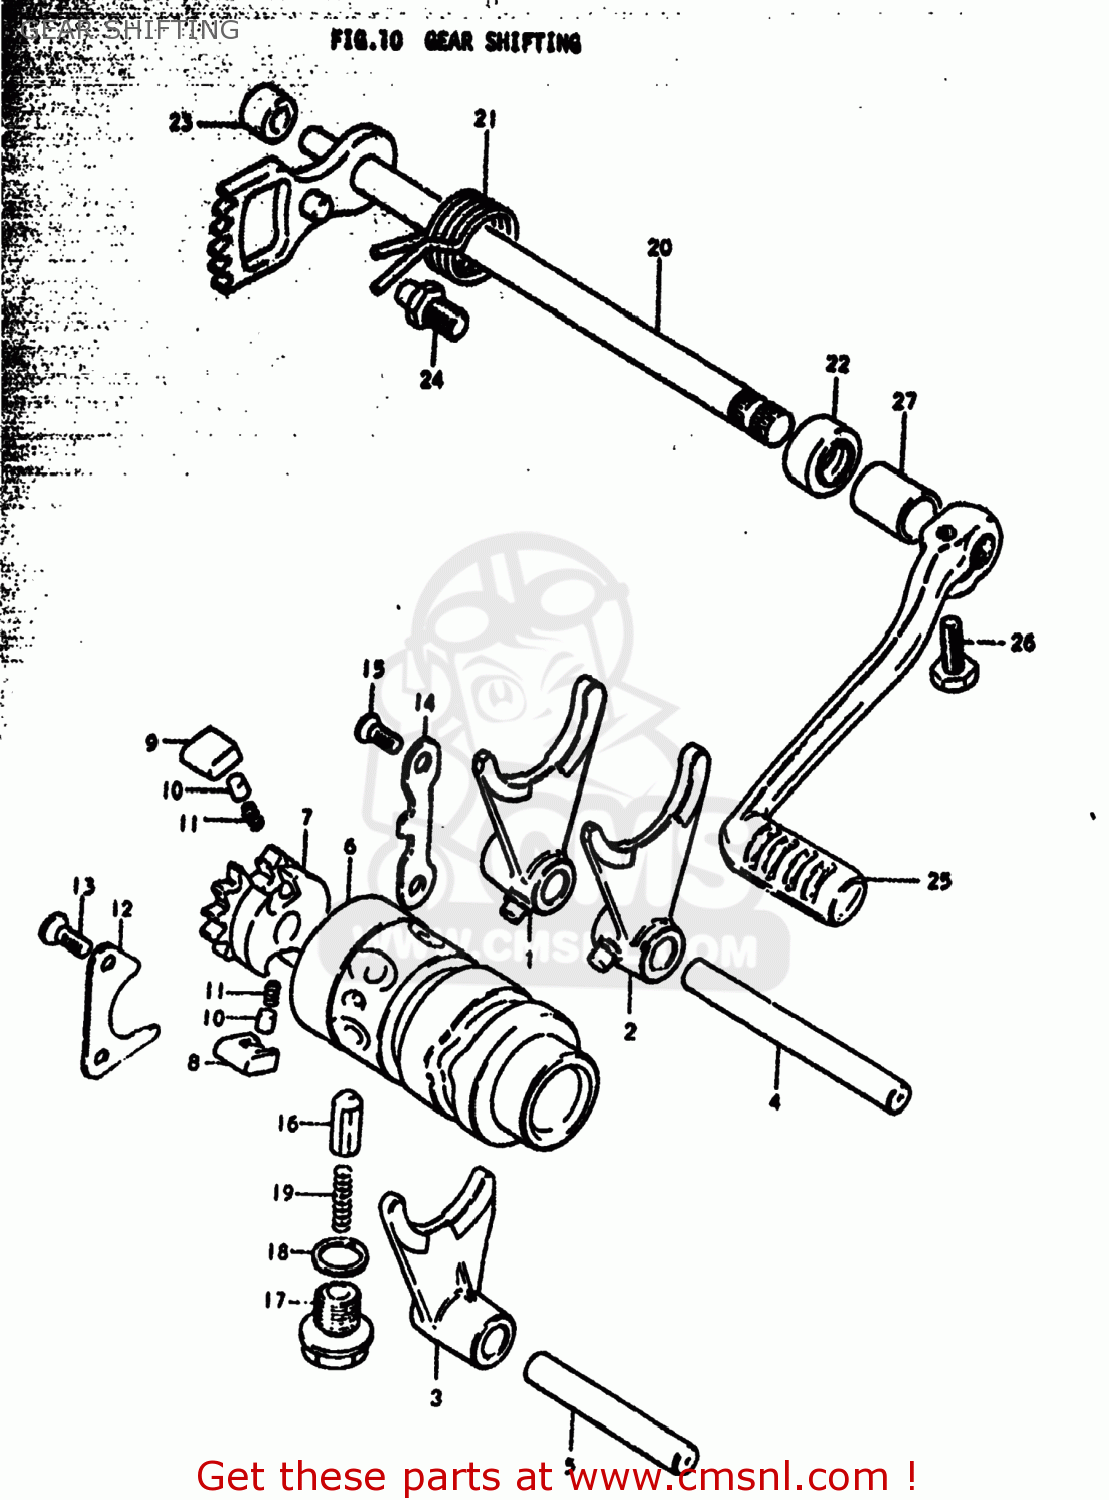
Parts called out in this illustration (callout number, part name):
1	FORK,GEAR SHIFT NO.1
2	FORK,GEAR SHIFT NO.2
3	FORK,GEAR SHIFT NO.3
4	SHAFT,GEAR SHIFT FORK
5	SHAFT,GEAR SHIFT FORK
6	CAM,GEAR SHIFT
7	RETAINER,GEAR SHIFT CAM
8	PAWL,GEAR SHIFT NO.1
9	PAWL,GEAR SHIFT NO.2
10	PIN(5X8)
11	SPRING
12	LIFTER,GEAR SHIFT PAWL
13	SCREW
14	GUIDE,GEAR SHIFT CAM
15	SCREW
16	STOPPER,GEAR SHIFTING
17	BOLT,GEAR SHAFT CAM STOPPER
18	GASKET(14X19.2X2) (NAS)
19	SPRING
20	SHAFT,GEAR SHIFT
21	SPRING
22	OIL SEAL
23	SPACER(12X20X15.3)
24	STOPPER,GEAR SHIFT CAM
25	LEVER,GEAR SHIFT
26	BOLT
27	CUSHION
